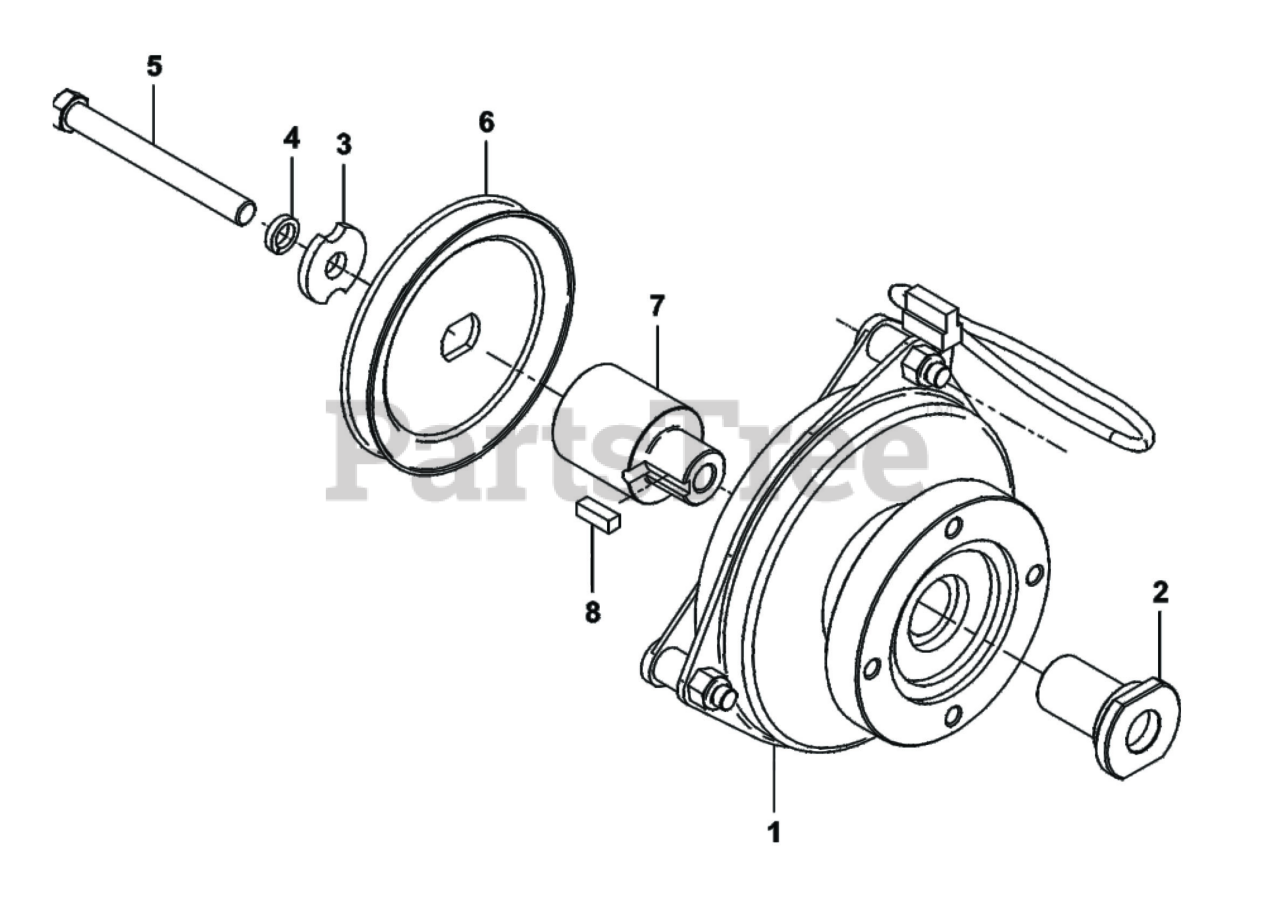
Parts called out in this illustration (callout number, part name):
1	ELECTRIC CLUTCH (110 FT-LBS)
2	CLUTCH SHAFT
3	WASHER-7/16 x 1-3/
4	LOCK WASHER 7/16"
5	SCREW 7/16"-20 X 4"
7	ENGINE PULLEY BUSHING #27
8	KEY, 1/4" X 3/4" LG
